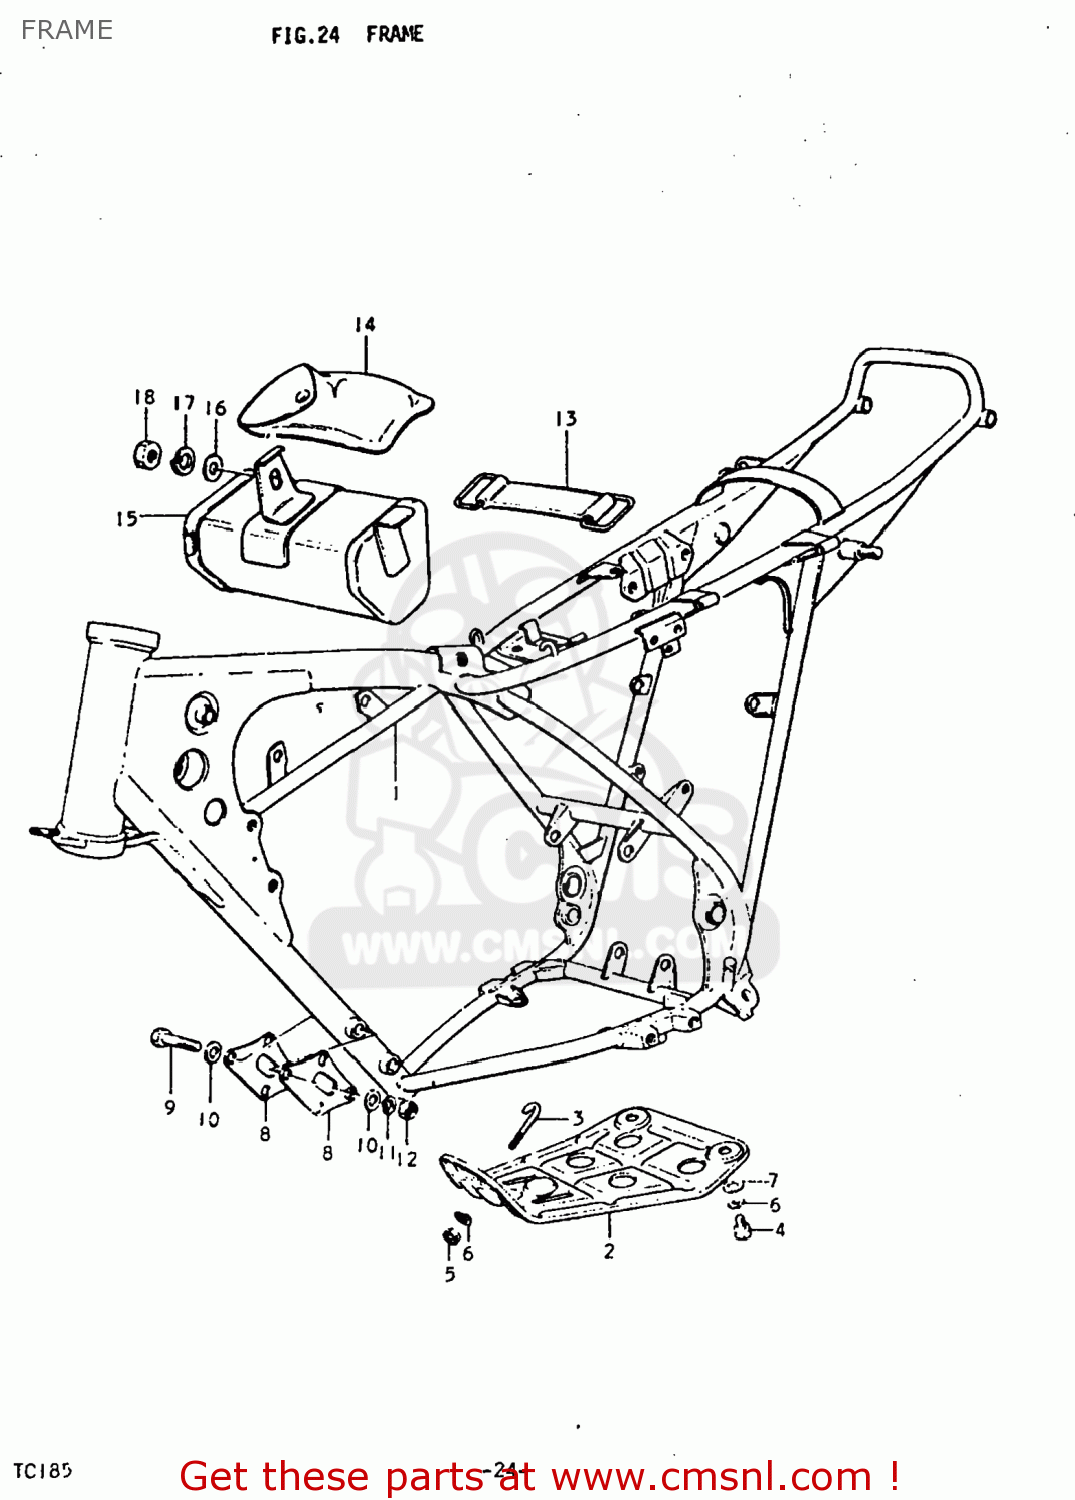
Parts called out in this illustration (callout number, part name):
1	FRAME
2	GROMMET
3	BRACKET,ENGINE PROTECT
4	BOLT
5	NUT
6	LOCK WASHER
7	WASHER
8	PLATE,ENGINE MOUNTING
9	BOLT
10	WASHER
11	LOCK WASHER
12	NUT
13	BAND
14	TOOL SET
15	HOLDER,TOOL
16	WASHER
17	LOCK WASHER
18	NUT
